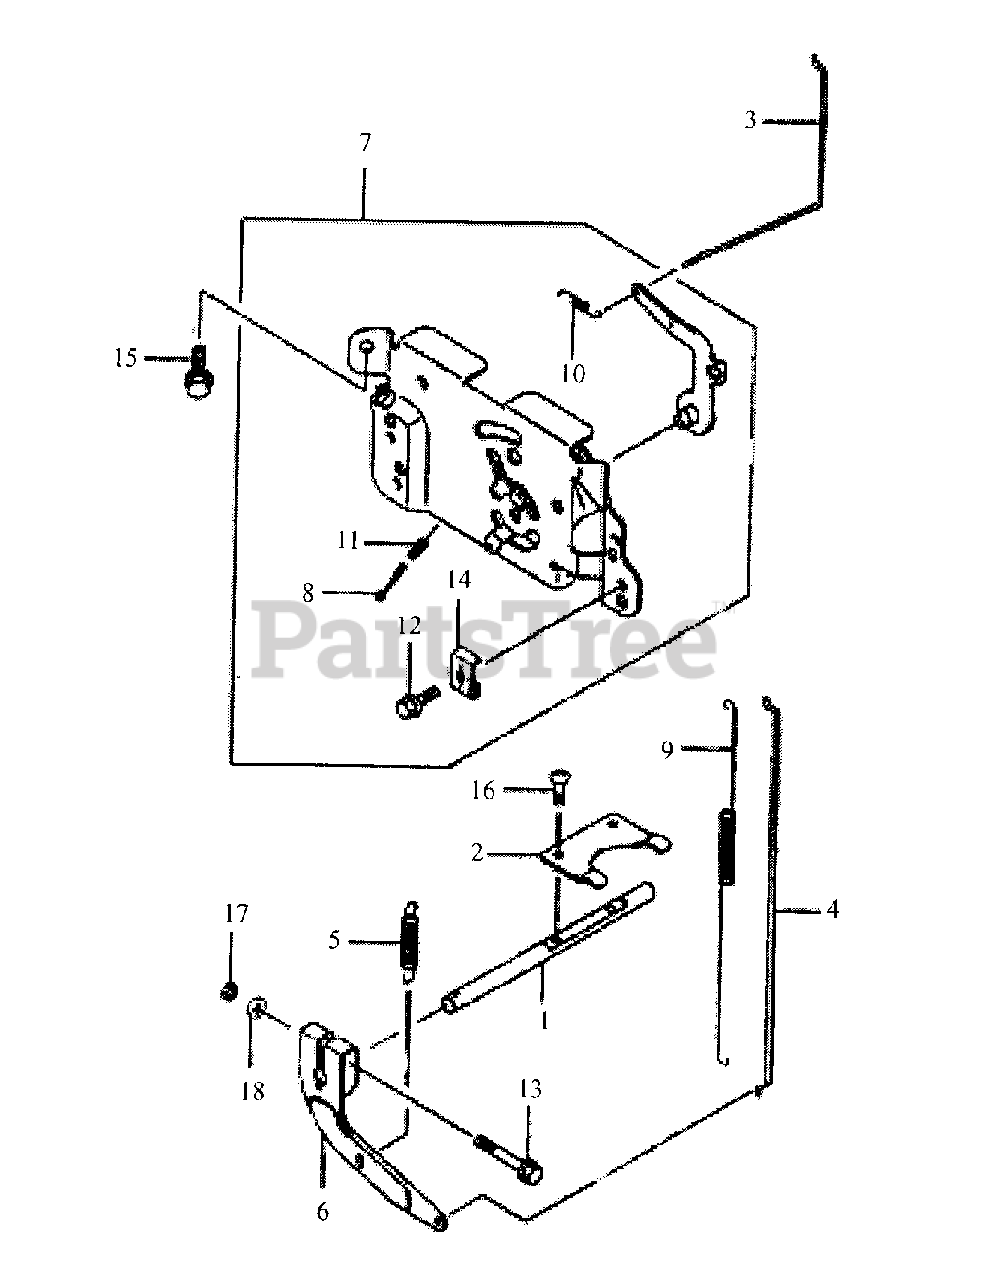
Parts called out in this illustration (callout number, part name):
1	Shaft
3	Link, Choke
5	Spring, Governor
6	Arm, Governor
7	Panel, Control
8	Screw 400
10	Spring
12	Bolt 5x 18
13	Bolt 6x30
15	Bolt, Flange
16	Screw, Pan
18	Washer, Plain
